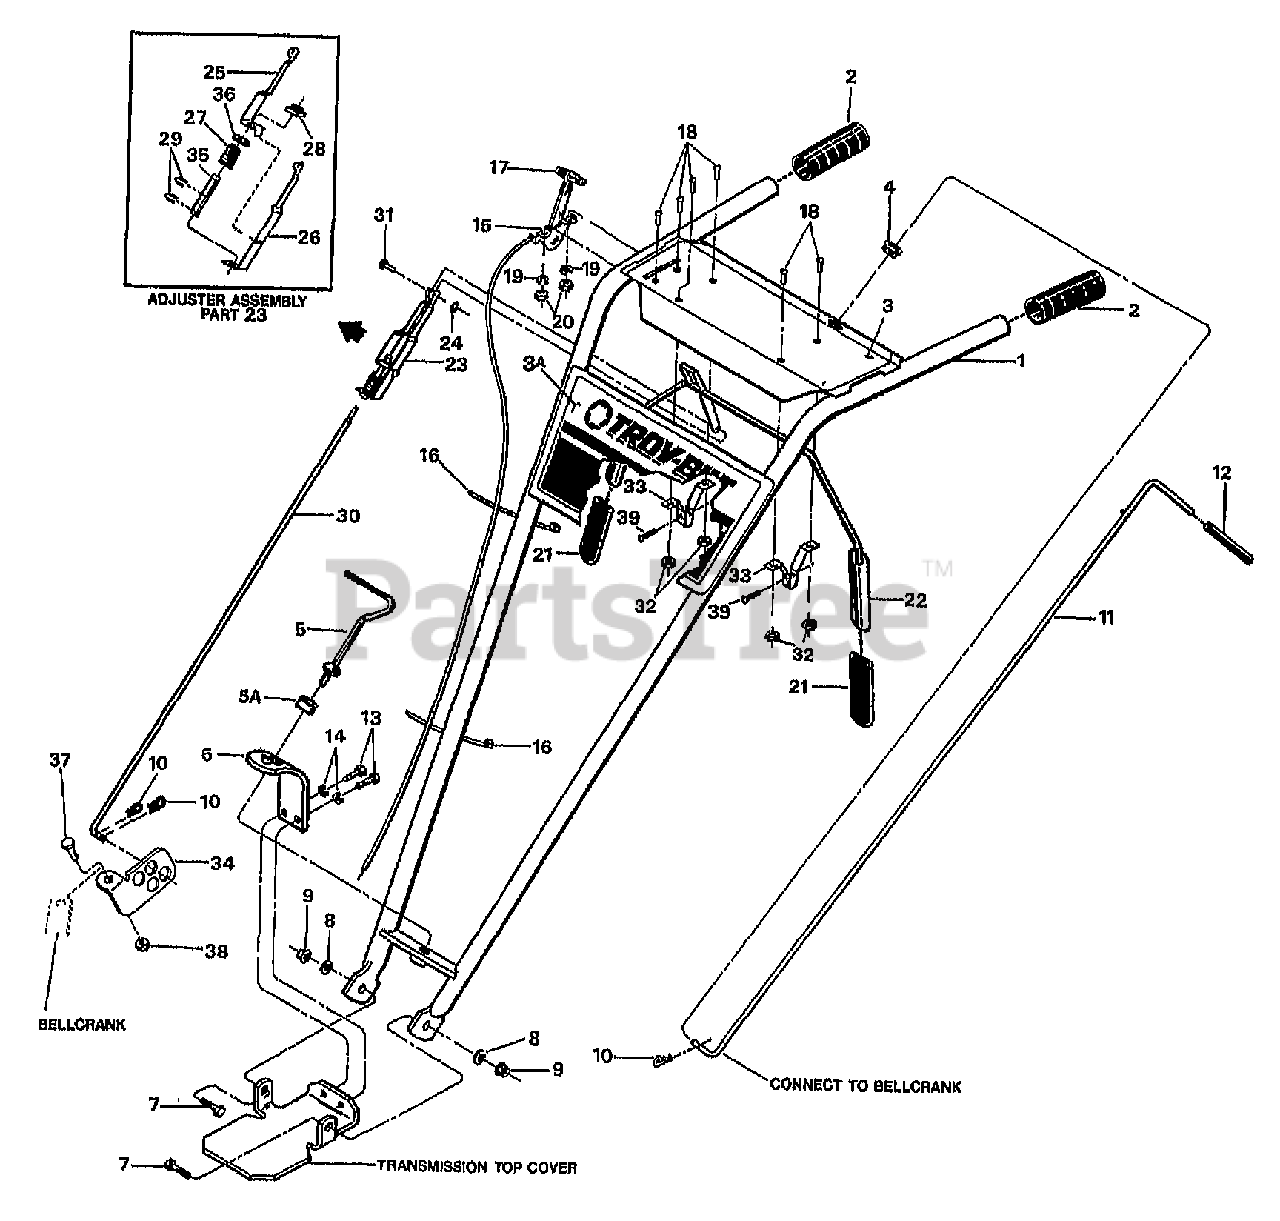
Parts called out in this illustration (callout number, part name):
1	ASSM-HANDLEBAR W/GRIPS (INCL. 2,3,3A,4)
2	GRIP-H/B 1" PONY/P-J OPC
3	DECAL-CONTROL PANEL JR
3A	DECAL-GRAPHICS PANEL JR
4	BUSHING-NYLON
5	ASSM-STUD H/B
5A	WASHER-1.0X.38X.375
6	PLATE-HANDLEBAR ADJUST
7	SCR-HH 3/8-16X1.0 G5 ZP
8	WASHER-FLAT 3/8 SAE
9	NUT-LOCK 3/8-16 NYLON ZP
10	PIN-CLIP .08
11	ROD-REV W/GRIP OPC (INCL. 12)
12	GRIP-CONTROL ROD
13	SCR-HH 3/8-16X.75 G5 ZP
14	WASHER-LK .375 @ DEPL
15	CABLE-THROTTLE JR OPC
16	TIE-RED
17	KNOB-THROTTLE CABLE
18	SCR-RH M10-32X.5 MACH
19	WASHER-LK M10
20	NUT-HH M10-32X.125
21	GRIP-PADDLE SM FRAME OPC
22	BAIL W/GRIPS OPC (INCL. 2 NO. 21)
23	ASSM-ADJUSTMENT OPC (INCL. 25,26,27,29, 35, 36)
24	RING-KLIP .188 DIA
25	ADJUSTER-RT SIDE OPC
26	ADJUSTER-LT SIDE OPC
27	SPRING-ADJUSTER OPC
28	WELDNUT 5/16-18
29	RING-KLIP .500 ZINC
30	ROD-CONTROL OPC
31	ASSM-PIN & CLIP (SMALL FRAME)
32	NUT W/LKWASHER #10-32 ZP
33	BRACKET-BAIL OPC
34	SWIVEL-SMALL FRAME
35	BUSHING-.5X.334X2.88
36	WASHER-.75X.51X.06 ZP
37	SCR-HH 1/4-20X.75 G5 ZP
38	NUT-LK 1/4-20
39	SCR-HWH 1/4-20 X .5 STH
